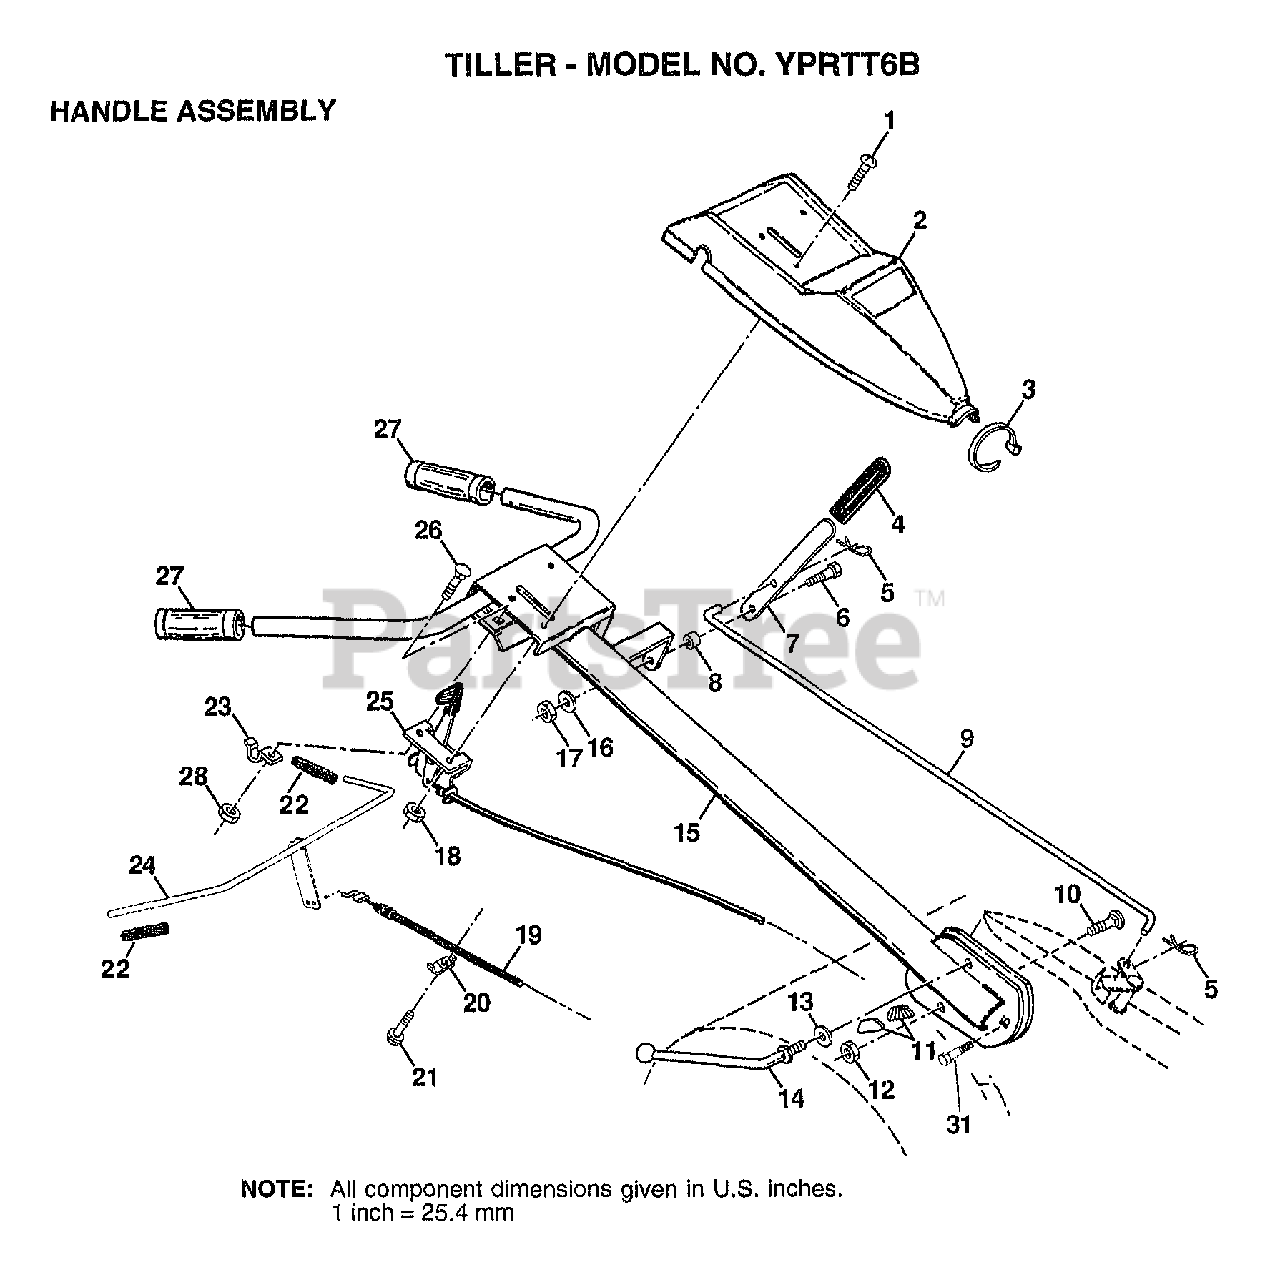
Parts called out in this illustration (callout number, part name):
1	SCREW.PNHD.10-24
2	"PANEL,CONT TI"
3	TIE CABLE CRT
4	GRIP T
5	RETAINER M
6	SHOULDER BOLT ST
7	SHIFT HANDLE CRT
8	GROMMET CRT
9	SHIFT ROD CRT
10	BOLT D
11	LOCK CRT
12	LOCKNUT
13	WASHER CRT
14	LEVER LOCK CRT
16	LOCKWASHER
19	CABLE.CLUTCH
20	CONDIUT CLIP T
22	GRIP BAR CRT
24	BAR ASM CONTROL
25	CONTROL.THROTTLE
26	BOLT
28	NUT
31	BOLT PIVOT
